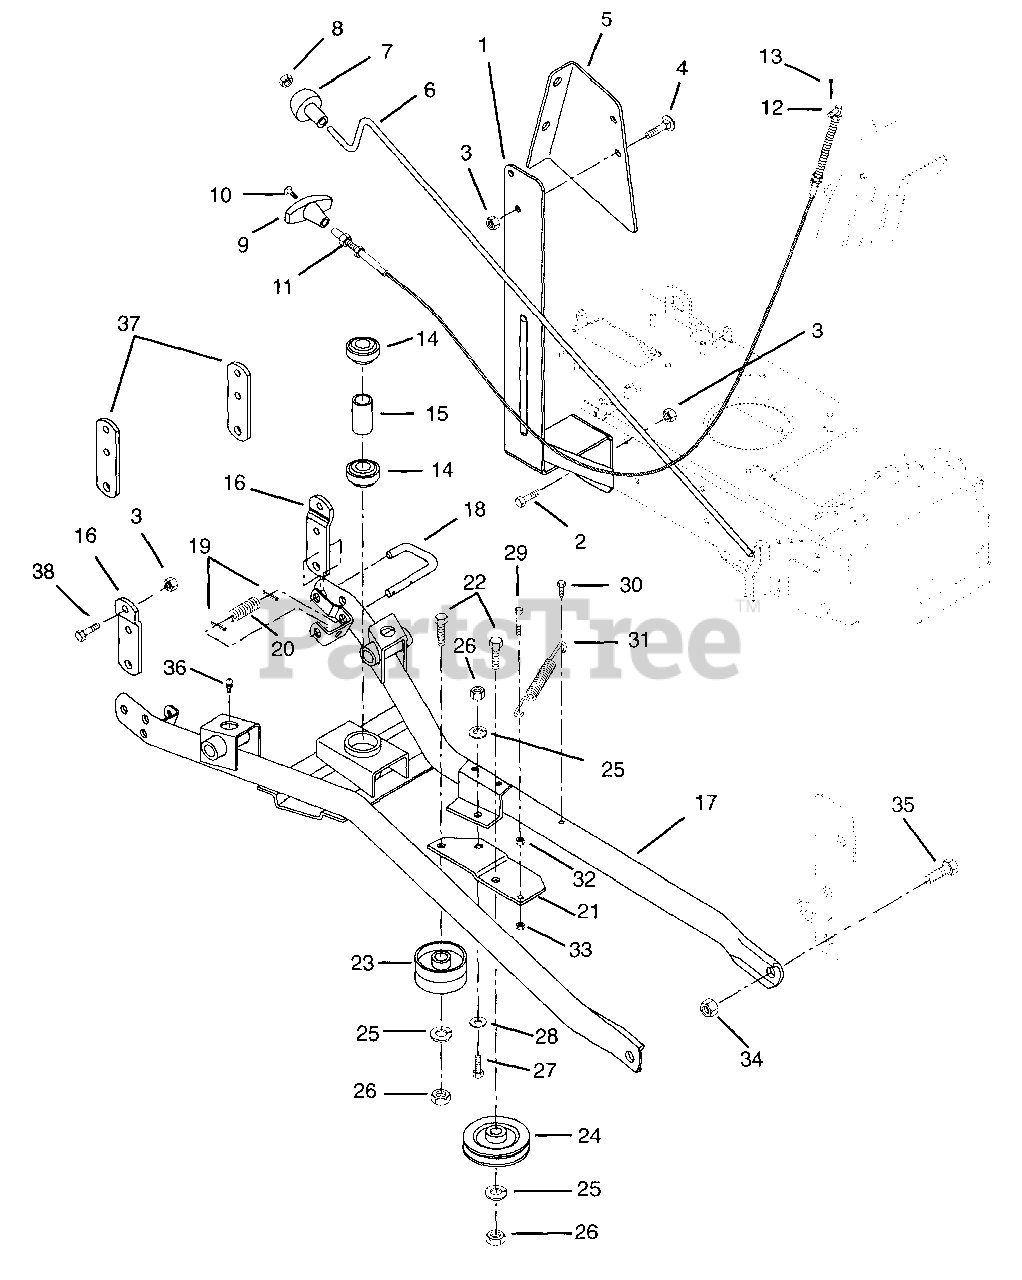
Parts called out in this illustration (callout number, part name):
1	SUPPORT - CONTROL BRACKET
2	@BLT-HEX .38-16X.75 GR5 YWZC
3	@NUT-LK-CTR .38-16 YWZC
4	BLT-RDHDSQNK .375-16X.75 GR5PL
5	CONTROL BRACKET
6	CHUTE CONTROL CRANK
8	@NUT-LK-CTR-JAM .375-16 YWZC
9	KNOB-BLACK
10	SCR-MCH 8-32X.75 PN HD YWZC
11	CONTROL CABLE
13	@PIN-CTR .09X.75 EXTPRSQCT YWZ
14	BRG-BALL .750X1.781X.61
15	SPACER .765X1.000X1.252
16	HANGER BRACKET- OFFSET
17	CARRIAGE FRAME W/ SPINDLE&BRGS
18	LATCH PIN
19	PIN-ROLL .125X.75
20	SPRG, COMP .058X.65X2.13 WLD15
21	IDLER ARM
22	@BLT-HEX .38-16X1.75 GR5 YWZC
23	IDLER-FLAT 2.25 X .38
24	IDLER-V 3.06 X .38
25	@WSHR-LK .38X.094 REG YWZC
26	@NUT-HEX .38-16 YWZC
27	SHOULDER BOLT .50 X .281
28	WSHR-FL-STL.511X1.441X.125 YWZ
29	SCR-TAP 10-24X1.0 HWH PL TR
30	@SCR-TAP .31-18X.75 HWH TR YWZ
31	SG-TENS .090X.75X3.50 WLD 34
32	@NUT-HEX 10-24 YWZC
33	@NUT-LK-NYL 10-24 W/INSRT YWZC
34	@NUT-LK-CTR .62-11 YWZC
35	@BLT-HEX .62-11X1.50 GR5 YWZC
36	FTG-LUBE .25-28X.256 YWZC
37	HANGER BRACKET
38	@BLT-HEX .38-16X1.00 GR5 YWZC
